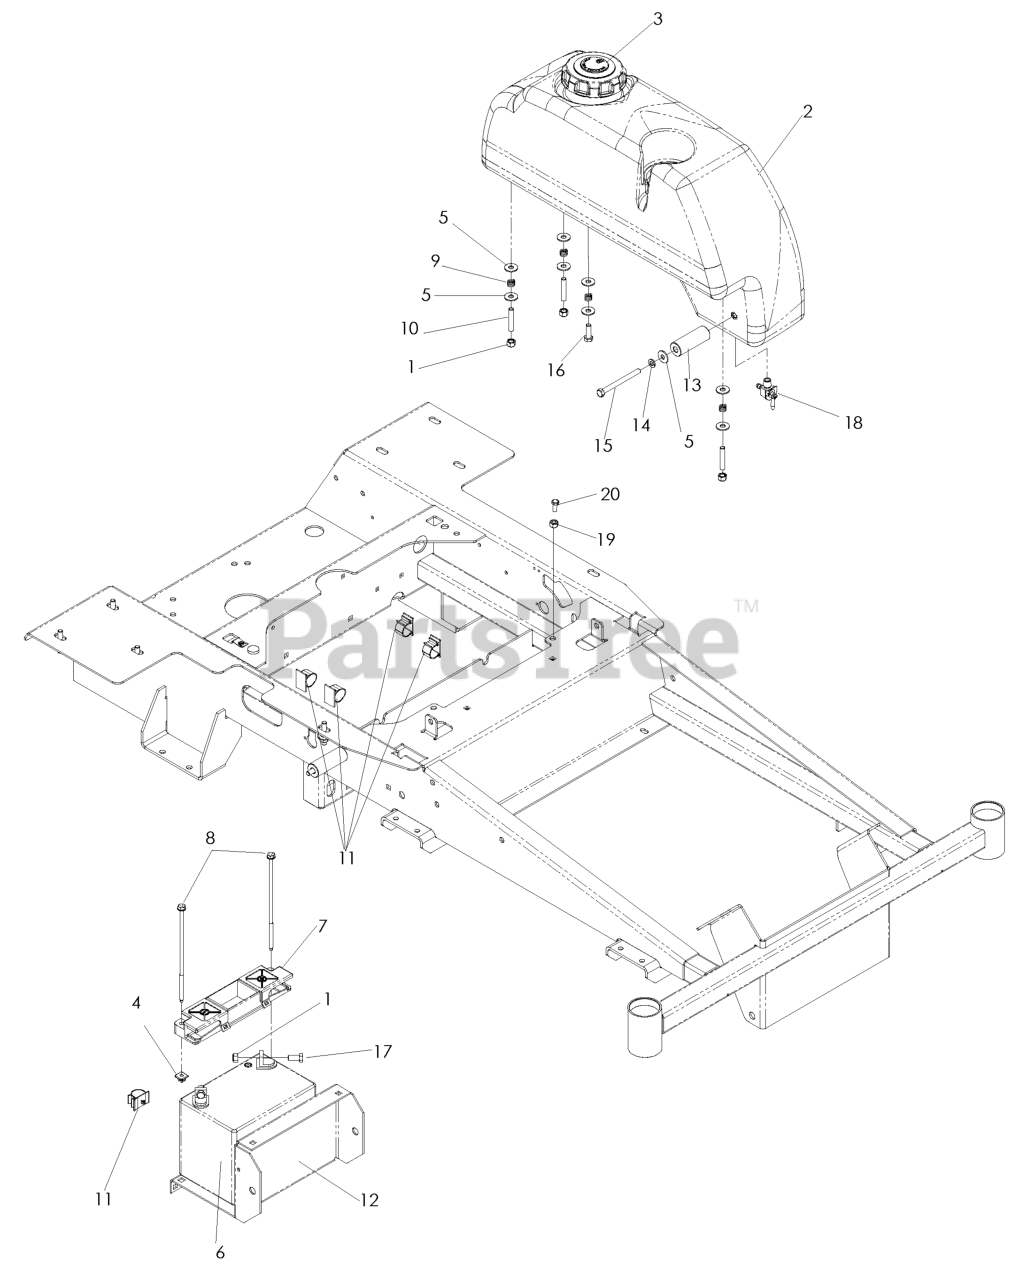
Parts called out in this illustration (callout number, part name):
1	NUT 5/16 NYLOC
2	LEFT TANK W/CUP HOLDER
3	FUEL CAP ANTI-SPLASH
4	PUSH NUT-NYLON
5	WASHER 5/16 FLAT
6	BATTERY, 12 V 330 AMP
7	BATTERY HOLD DOWN
8	BOLT - 1/4-20 X 7.5
10	STUD, 5/16C
11	PUSH-MOUNT WIRE CLIP
12	BATTERY TRAY
13	TANK SPACER
14	WASHER.LOCK.HVY.HLCL.SPR.5/16
15	BOLT - HCS 5/16C X 3.5
16	HCS 5/16C X 1
17	HCS 5/16C X 3/4
18	FUEL VALVE
19	NUT 5/16C HEX
20	HCS 5/16-18X1-3/4 TPBLT
